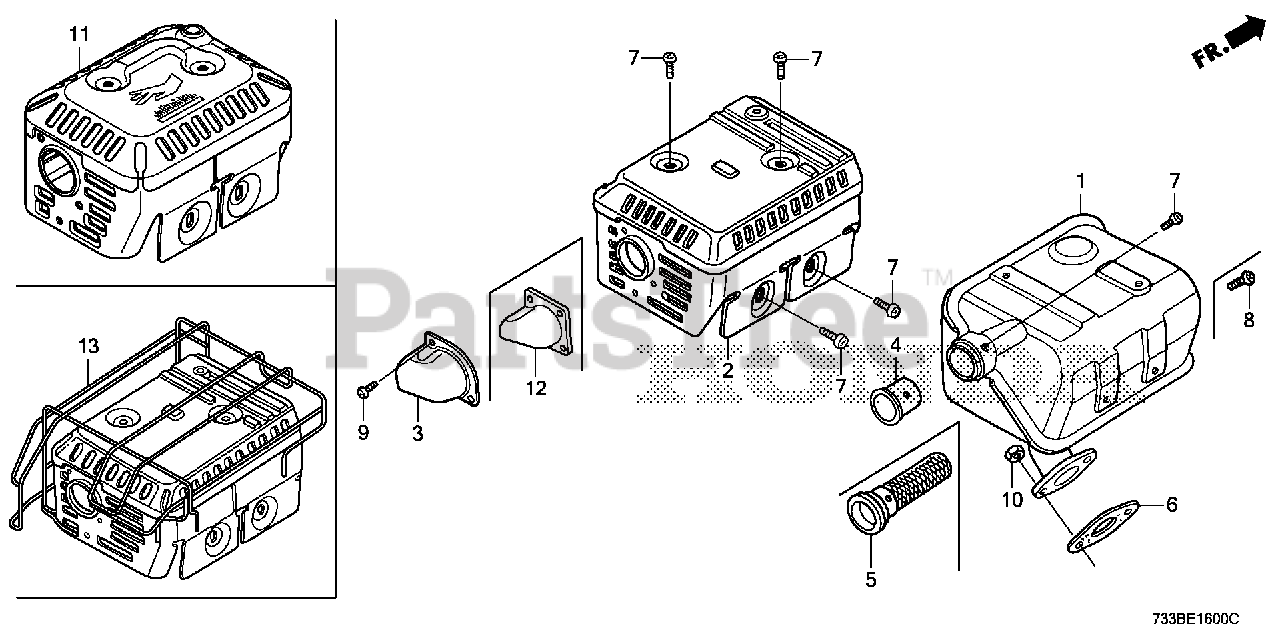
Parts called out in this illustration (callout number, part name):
1	MUFFLER (STD) Use up to Engine SN 1869307.
1	MUFFLER (ARRESTER) (SPARK ARRESTER TYPE)
2	PROTECTOR, MUFFLER (STD) (BLACK)
3	DEFLECTOR, MUFFLER
4	PIPE, TAIL
5	ARRESTER, SPARK
6	GASKET, MUFFLER
7	SCREW, TAPPING (5X8)
8	SCREW, TAPPING (4X6) (TO INSTALL OPTIONAL SPARK ARRESTER)
9	SCREW, TAPPING (4X6)
10	NUT, HEX. (8MM)
